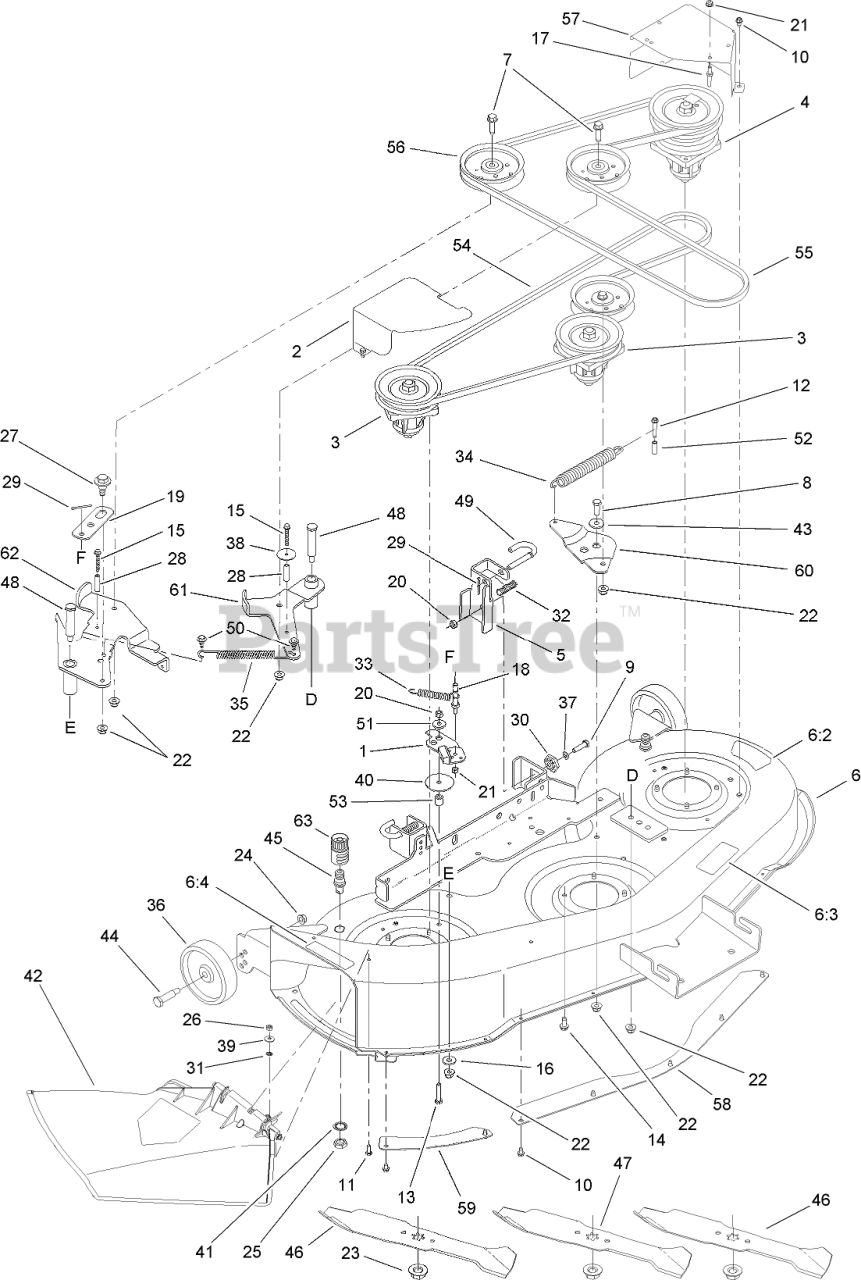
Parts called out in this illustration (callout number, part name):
1	DECK BRAKE BRACKET ASM
2	COVER-BELT, RH
3	SPINDLE ASM
4	DOUBLE PULLEY SPINDLE ASM
5	LH HANGER BRACKET ASM
6	DECK AND DECAL ASM
6:2	DECAL-DANGER
6:3	DECAL-ROUTING, BELT
6:4	DECAL-DANGER
7	SCREW-HH
8	SCREW-HH
9	SCREW-HH
10	SCREW-HWHTF
11	SCREW-HH
12	SCREW-HWH
13	SCREW-HH
14	SCREW-HWH
15	SCREW-HH
16	WASHER-FLAT
17	PIN-GUARD, BELT
19	BRACKET-BRAKE
20	NUT-LOCK, FLANGE
21	NUT-LOCK, FLANGE
22	NUT-LOCK, FLANGE
23	NUT-LOCK, FLANGE
24	NUT-LOCK, FLANGE
25	NUT-HEX
26	NUT-HEX
27	BOLT-SHOULDER
28	SPACER
29	PIN-COTTER
30	GEAR-ADJUSTMENT, DECK
31	RETAINER-BOLT
32	SPRING-COMPRESSION
33	SPRING-EXTENSION
34	SPRING-EXTENSION
35	SPRING-EXTENSION
36	WHEEL-DECK, REAR
37	WASHER-LOCK
38	WASHER-FLAT
39	WASHER-SPRING
40	WASHER-FLAT
41	WASHER-LOCK
42	DISCHARGE CHUTE ASM
43	SPACER-SHOULDER
44	BOLT-SHOULDER
45	ADAPTER-NOZZLE, WATER
46	BLADE-16.28 INCH
47	BLADE-14.88 INCH
48	BOLT-SHOULDER
49	PIN-HANDLE, DECK RELEASE
50	BOLT-SHOULDER
51	SPACER-SHOULDER
52	SPACER
53	SPACER
55	BELT-V
56	PULLEY-IDLER
57	COVER-BELT, LH
58	SKIRT-CENTER, DECK
59	SKIRT-RH, DECK
60	BRACKET-IDLER
61	LH IDLER BRACKET ASM
62	RH IDLER BRACKET ASM
63	NOZZLE-WATER, DECK
